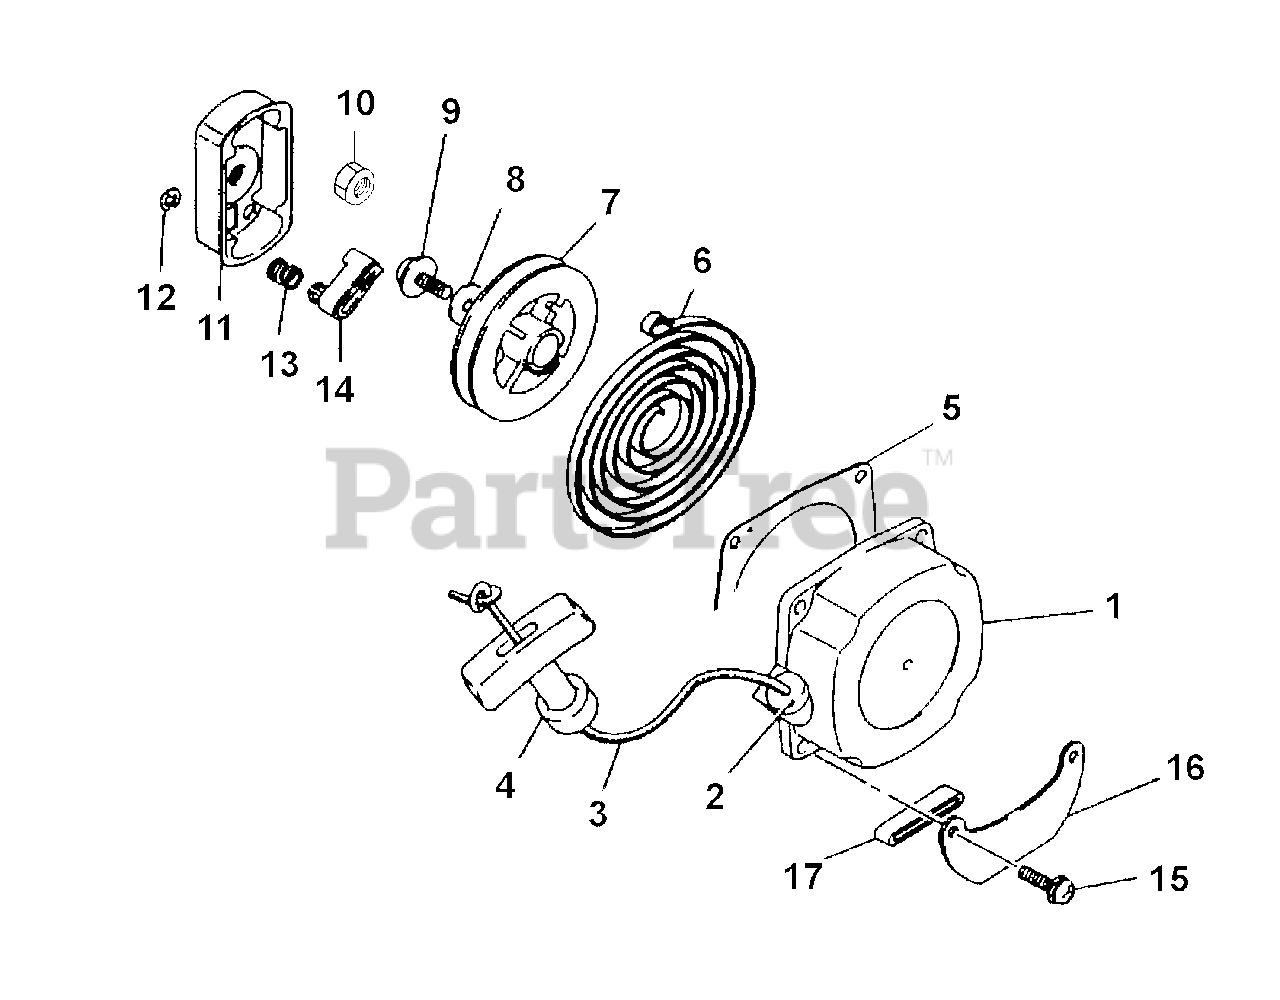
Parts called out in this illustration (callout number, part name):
1	Starter Assembly
9	Screw & Washer
10	Nut
11	Pulley Assembly
12	Snap Ring
13	Spring, Return
15	Screw & Washer
17	Pad, Bracket
